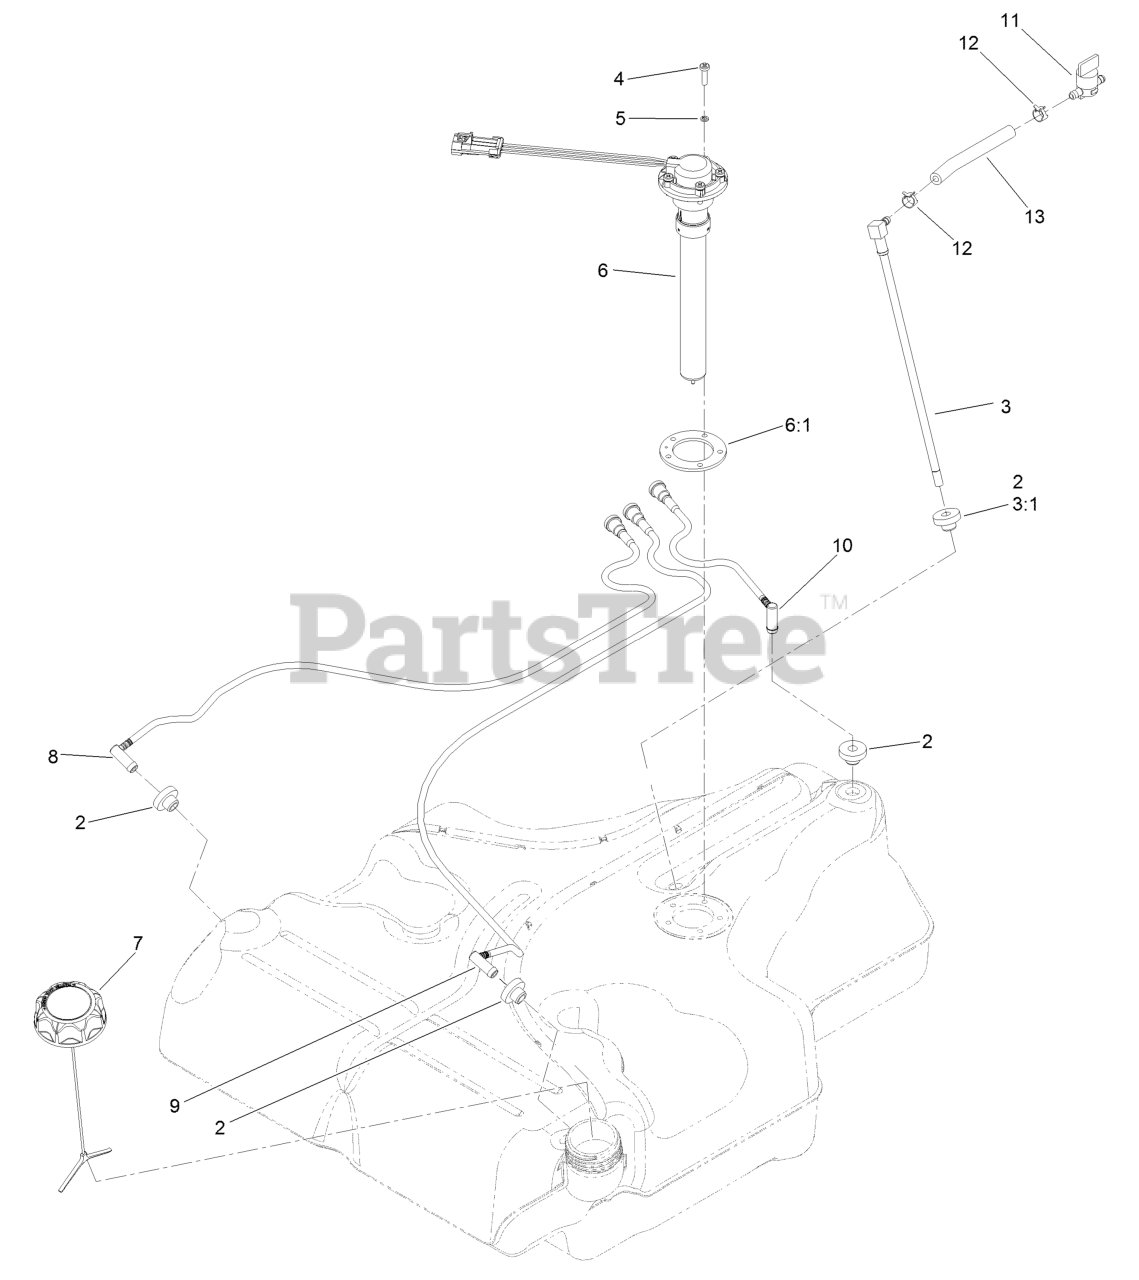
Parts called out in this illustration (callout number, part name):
2	BUSHING
3	FUEL LINE KIT (WITH GROMMET)
3:1	BUSHING
4	SCREW-PAN
5	WASHER-LOCK
6:1	GASKET-SENDER, FUEL
7	CAP-FUEL, RATCHETING
8	RH VENT LINE KIT (WITH GROMMET)
9	LH VENT LINE KIT (WITH GROMMET)
10	REAR VENT LINE KIT (WITH GROMMET)
11	VALVE-FUEL
12	CLAMP-HOSE
13	HOSE-FUEL
